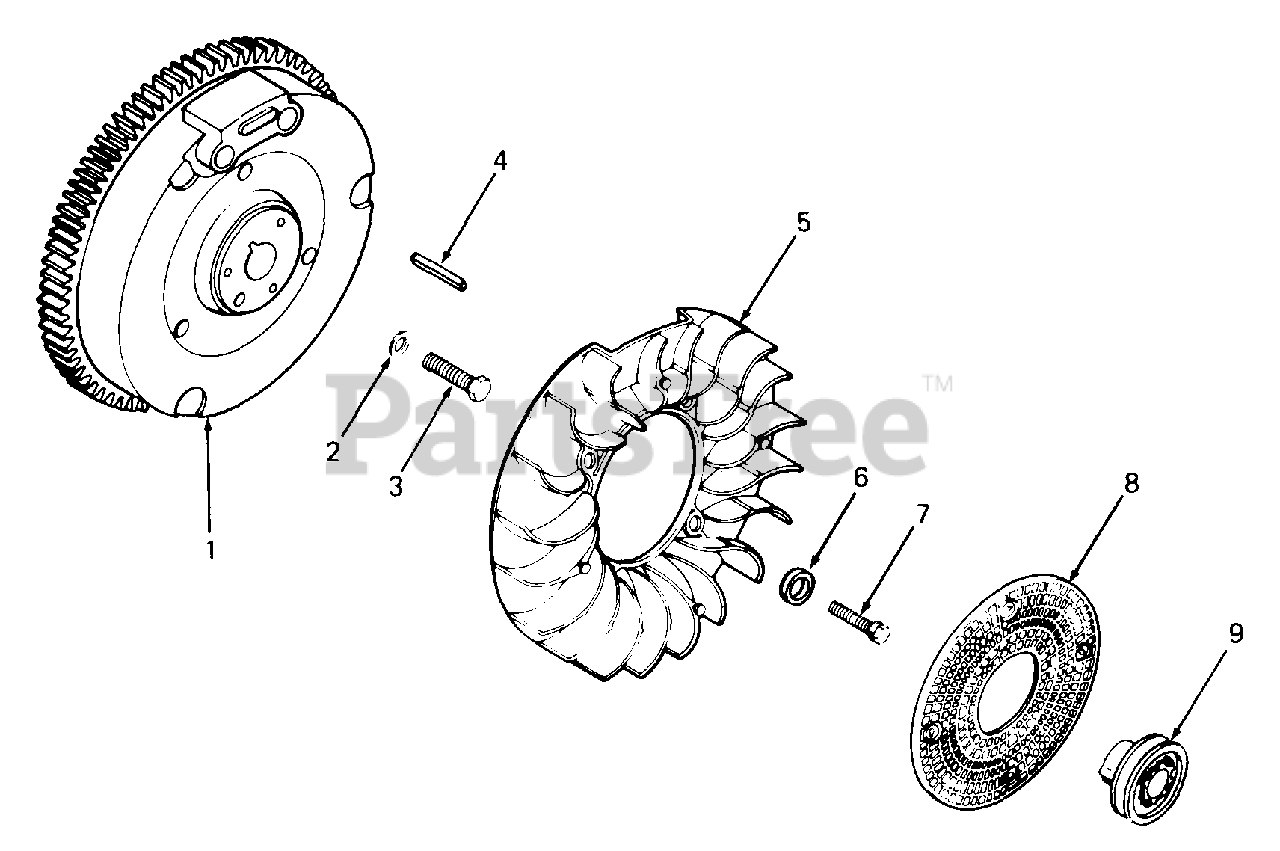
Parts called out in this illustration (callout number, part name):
2	Washer
3	Screw, Hex Mach, 3/8-24 X 1.25 Lg
4	Key, Square, 3/16 X 1.37
7	Screw, Hex Wash Hd, 1/4-20 X .62 Lg
8	Screen, Grass
9	Kit, Drive Cup
